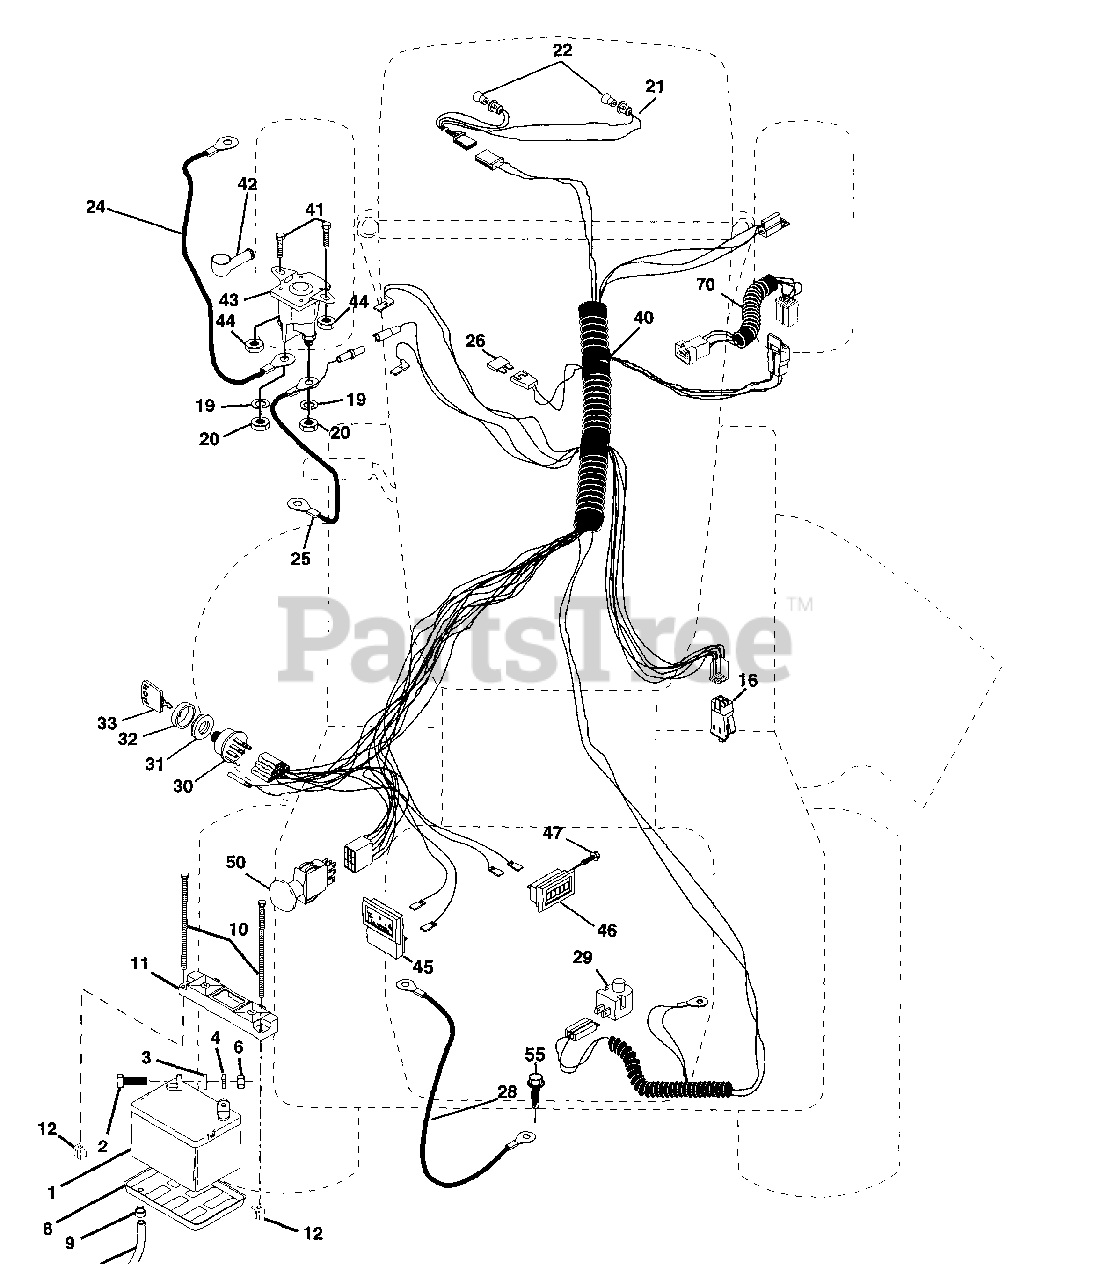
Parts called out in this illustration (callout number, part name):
1	Battery 12 Volt 35 AMP
2	Bolt Hex Hd 1/4-20unc X 3/4
3	Washer 9/32 X 5/8 X 16 Ga.
4	Washer Lock Hvy Helical 1/4
6	Nut Fin Hex 1/4-20 Unc
7	Tube Plastic 46" Front Battery
8	Case Battery Mech Hinge
9	Clamp Hose Olive
10	Bolt Brt Frt 1/4-20 x 75 Ainc
11	Holddown Battery Front Mount
12	Nut Push Nylon 1/4" Battery Frt
16	Switch Interlock Push-In
19	Washer Lock 1/4
20	Nut Jam Hex 1/4-20 Unc
21	Harness Asm Light W/4152j
22	Bulb Light #1156
24	Cable Battery 6 Ga 11" red
25	Cable Battery 6 Ga 22" red w/16 wire
26	Fuse 30 AMP Auto Green
28	Cable Ground 6 Ga 21" black
29	Switch Plunger Nc Gray
30	Switch Ign 4 pos w/lights
31	Nut Ignition
32	Cover Sw Ignition
33	Key Ign Modelled Generic
40	Harness ign.
41	Bolt Blk Fin Hex 1/4-20 x 1/2
42	Cover Terminal Red
43	Solenoid
44	Nut Keps Hex 1/4-20 Unc
45	Ammeter Rectangular 15 Amp
46	Meter Hour
47	Screw 10-24 x 1/2 Black
50	Switch PTO 3 PDT Black Delta 96
55	Screw Thdrol 5/16-18 x 1-1/2 Tyt
70	Harness, Eng.
